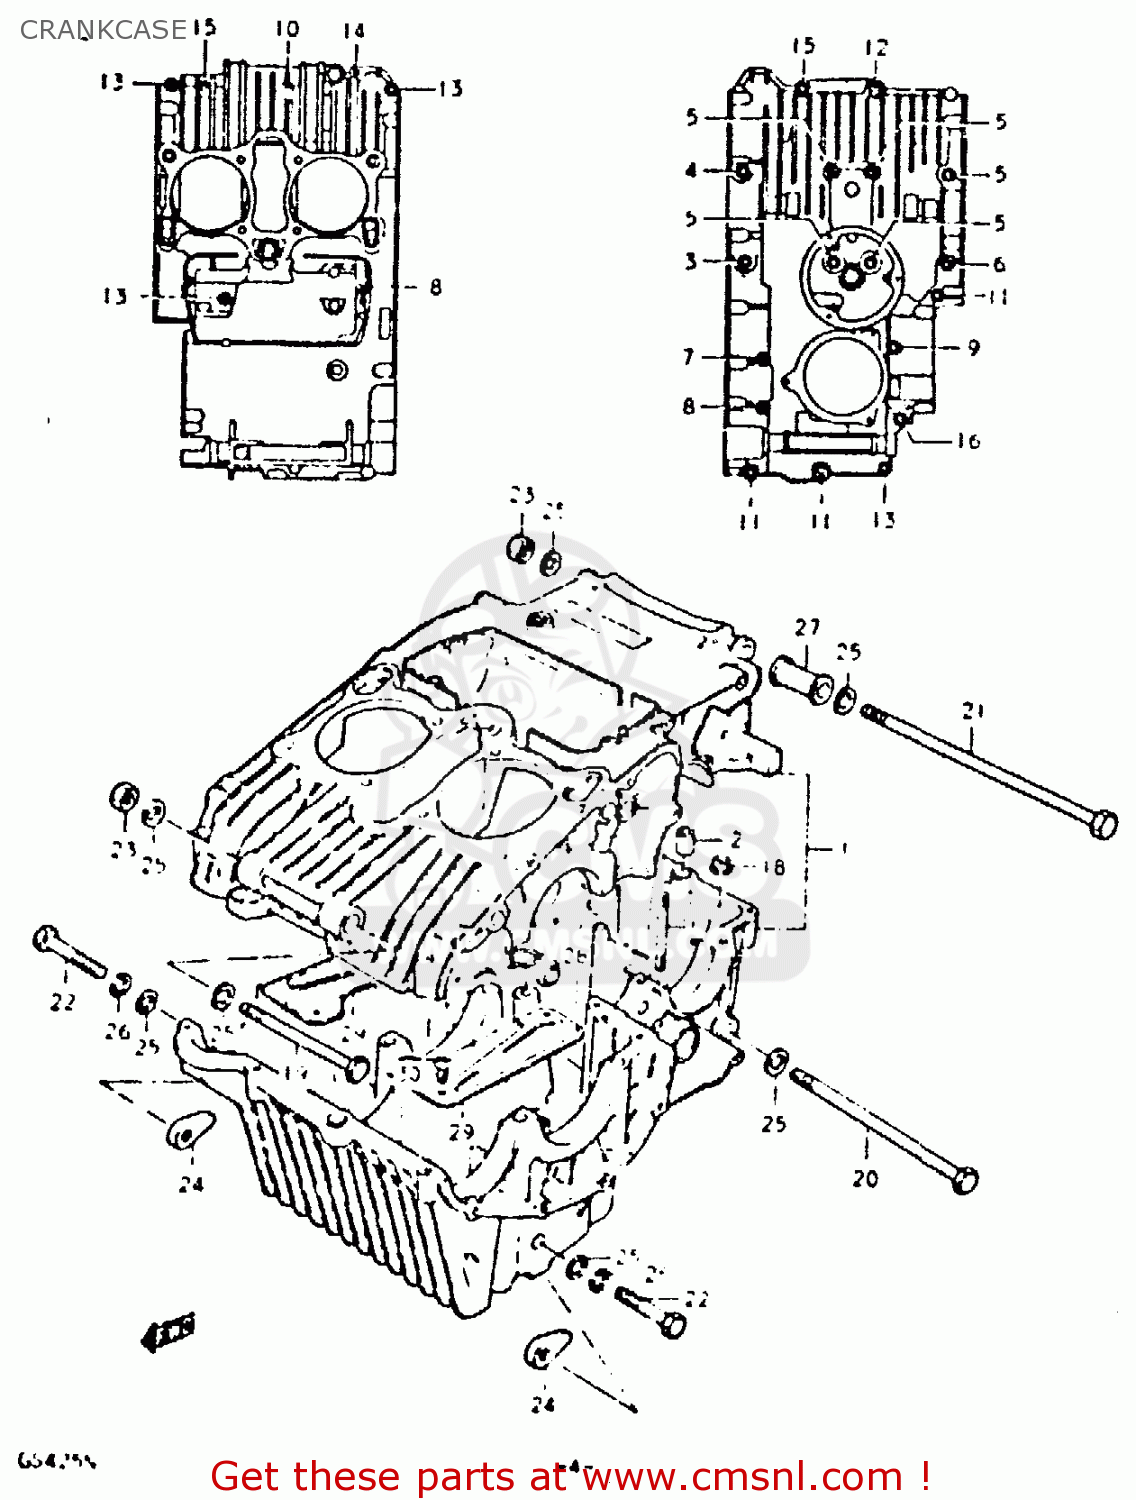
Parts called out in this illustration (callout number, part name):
1	CRANKCASE SET
2	PIN
3	BOLT
4	BOLT (8X95)
5	BOLT 8X90
6	BOLT
7	BOLT
8	BOLT (6X90)
9	BOLT (6X70)
10	BOLT 6X65
11	BOLT (6X60)
12	BOLT,UNDER
13	BOLT
14	BOLT 6X35
15	BOLT
16	BOLT (8X45)
17	STUD BOLT
18	NUT
19	BOLT
20	BOLT 10X160
21	BOLT 10X265
22	BOLT
23	NUT
24	NUT
25	WASHER
26	LOCK WASHER
27	SPACER,ENGINE MOUNT
28	O-RING
29	PLATE,OIL SEPARATOR
30	SCREW
